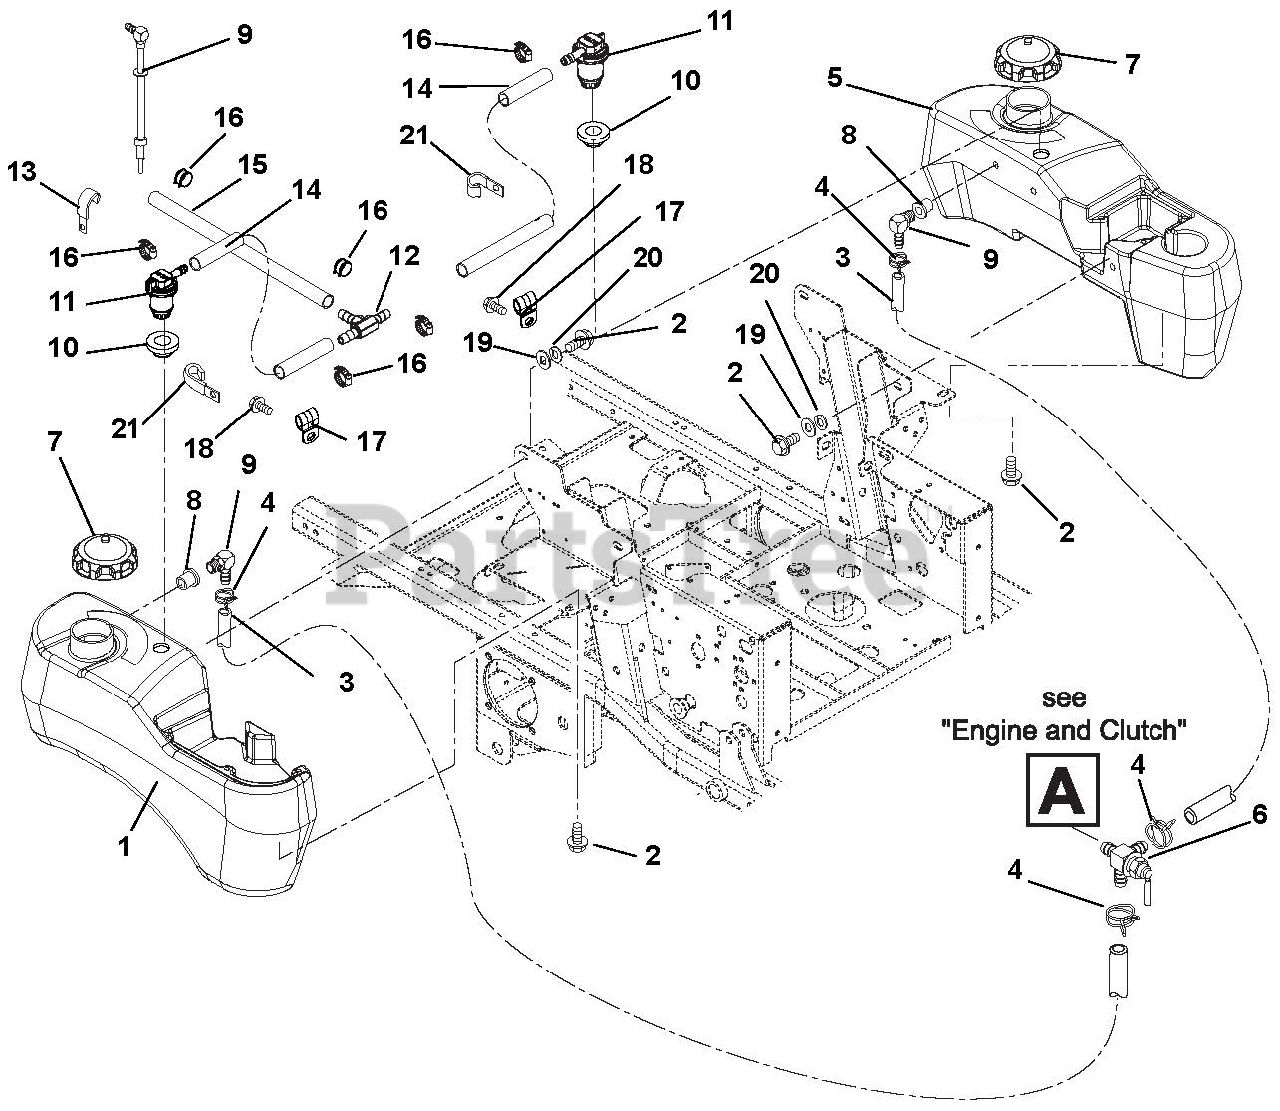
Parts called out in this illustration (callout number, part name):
1	Tank, Fuel Right Hand
2	Bolt-Hex .31-18X.75 Grade 5
3	Hose, .25 Low-PERM Bulk Gas, 3 @ 42"
4	Clamp, Fuel Line
5	Tank, Fuel Left Hand
6	Valve, Fuel
7	Cap, Fuel Vent-in Autolock
9	Assembly, Large Tank Fuel Pick-up
10	Grommet, Remote Vent Nitrile
11	Valve, 2-Way
12	Tee, 3/16" x 3/16" Branch
14	Hose, .188 Low-PERM Bulk Gas
15	Hose, .188 Low-PERM Bulk Gas
16	Clamp, Hose Spring .188
17	Clamp, Cushioned Steel
18	Screw, Tapping Hex Washer Head Thread Rolling .31-18 x .50
19	Washer-Flat-Steel .38X.875X.083
20	Washer-Locking .31X.078
